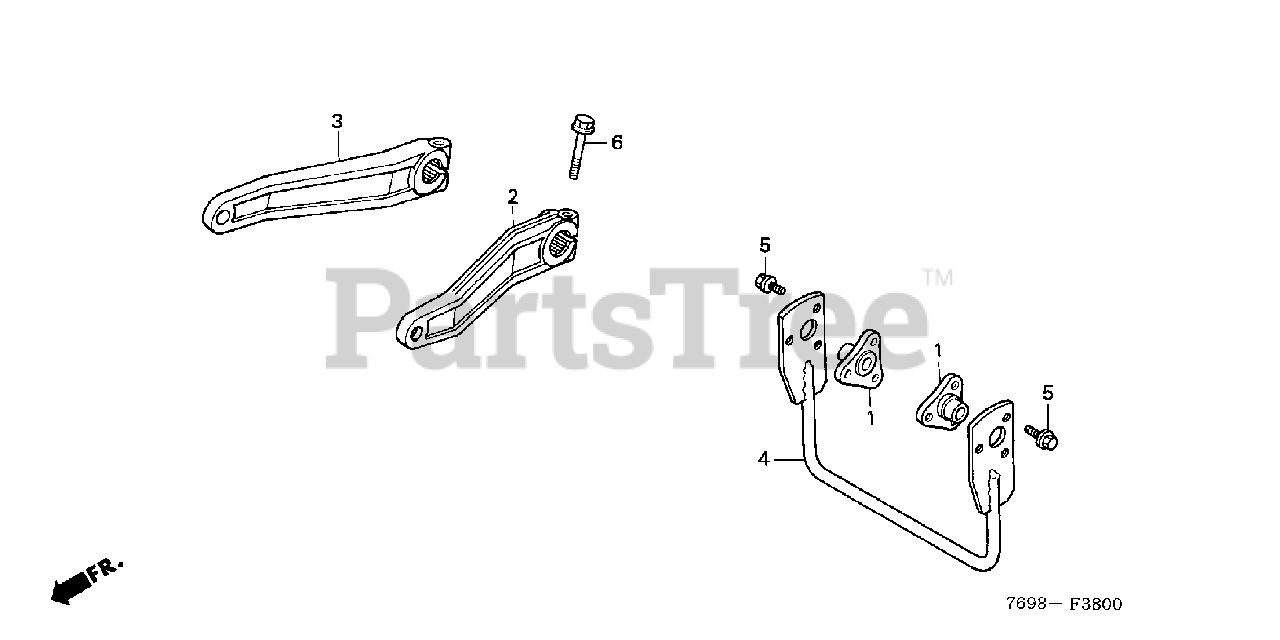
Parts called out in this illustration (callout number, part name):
1	PIVOT, FR. HITCH
2	ARM, L. FR. LIFT
3	ARM, R. FR. LIFT
4	GUARD, TENSIONER
5	BOLT, FLANGE (8X25)
6	BOLT, FLANGE (10X40)
